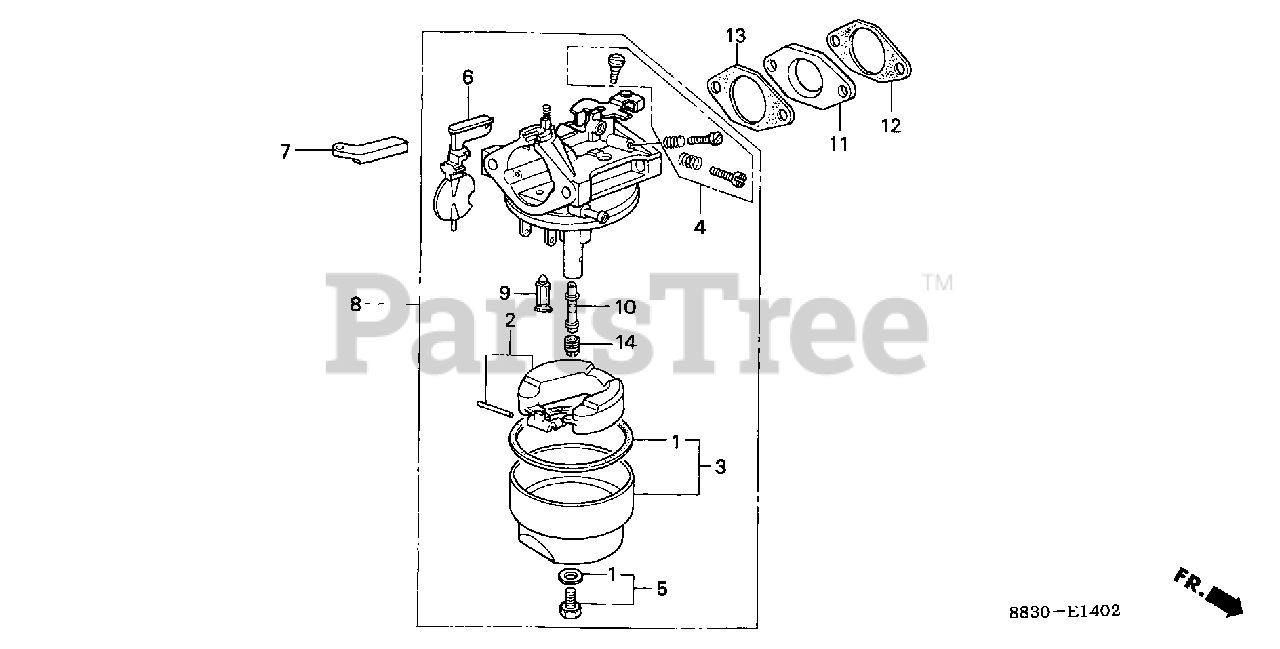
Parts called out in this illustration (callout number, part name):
1	GASKET SET
2	FLOAT SET (CARBURETOR NO.)
3	CHAMBER SET, FLOAT (CARBURETOR NO.) (NOT AVAILABLE)
4	SCREW SET A Use from Engine SN BB30C B.
4	SCREW SET A (CARBURETOR NO.)
5	SCREW SET
6	CHOKE SET (CARBURETOR NO.)
7	ARM, CHOKE LEVER
8	CARBURETOR ASSY. (BB30A G)
8	CARBURETOR ASSY. (BB30C B)
9	VALVE, FLOAT (CARBURETOR NO.)
10	NOZZLE, MAIN (CARBURETOR NO.)
11	INSULATOR, CARBURETOR
12	GASKET, INSULATOR
13	GASKET, CARBURETOR
14	JET, MAIN (#65) Use from Engine SN BB30C A.
14	JET, MAIN (#68) Use from Engine SN BB30C A.
14	JET, MAIN (#70) Use from Engine SN BB30C A.
14	JET, MAIN (#72) (CARBURETOR NO.)
